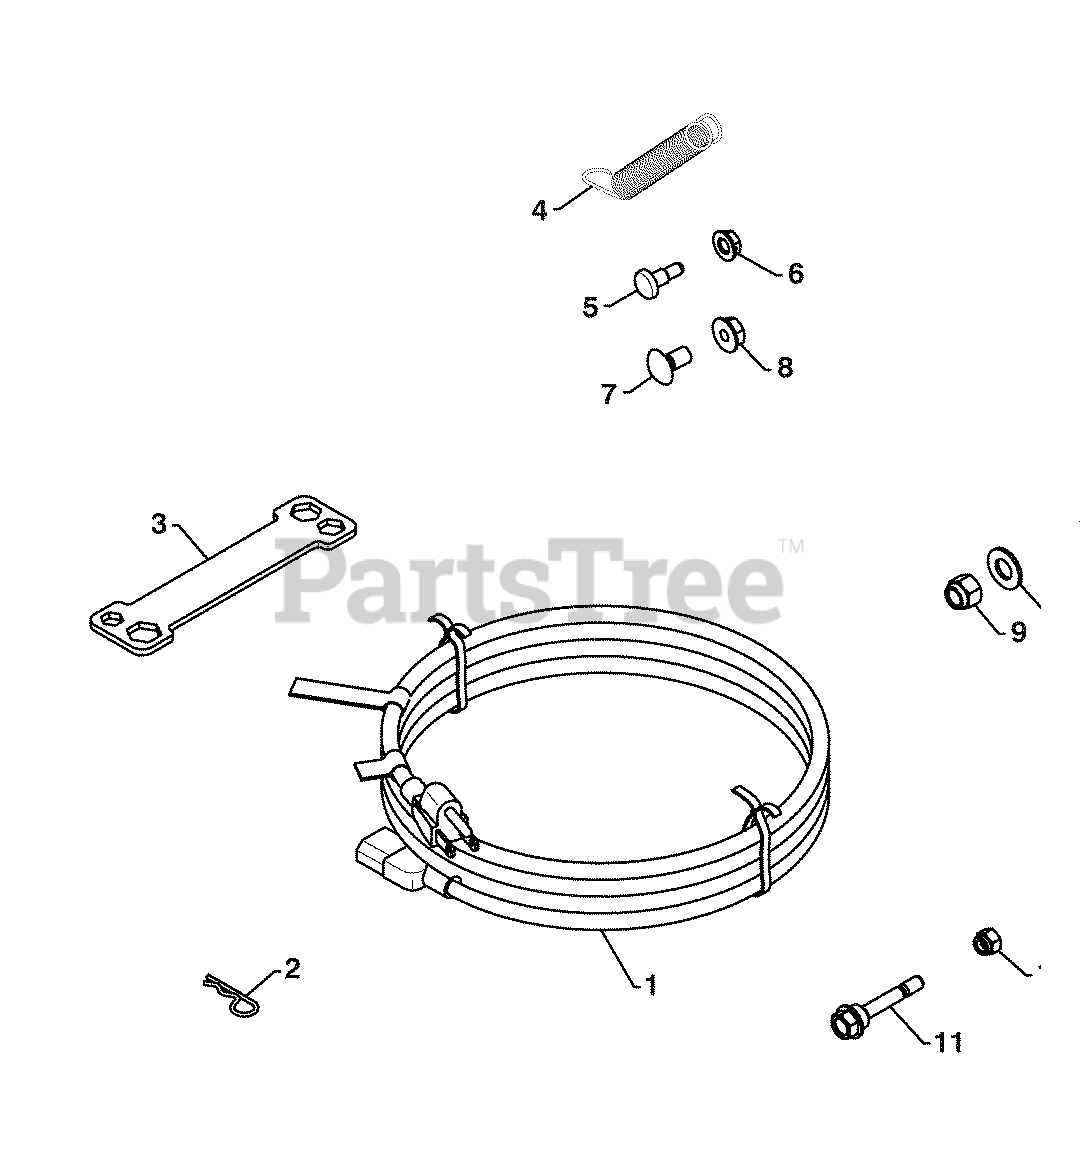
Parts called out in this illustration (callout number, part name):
1	POWER CORD
2	RETAINER PIN
4	REMOTE SPRING
5	SHOULDER BOLT 1/4-20
6	LOCKNUT 1/4-20
7	CARRIAGE BOLT 5/16-18 X 5/8
8	LOCKNUT 5/16-18
9	LOCKNUT 3/8-16
10	WASHER 3/8
11	SHEAR BOLT 1/4-20 X 1-13/16
12	LOCKNUT 1/4-20
